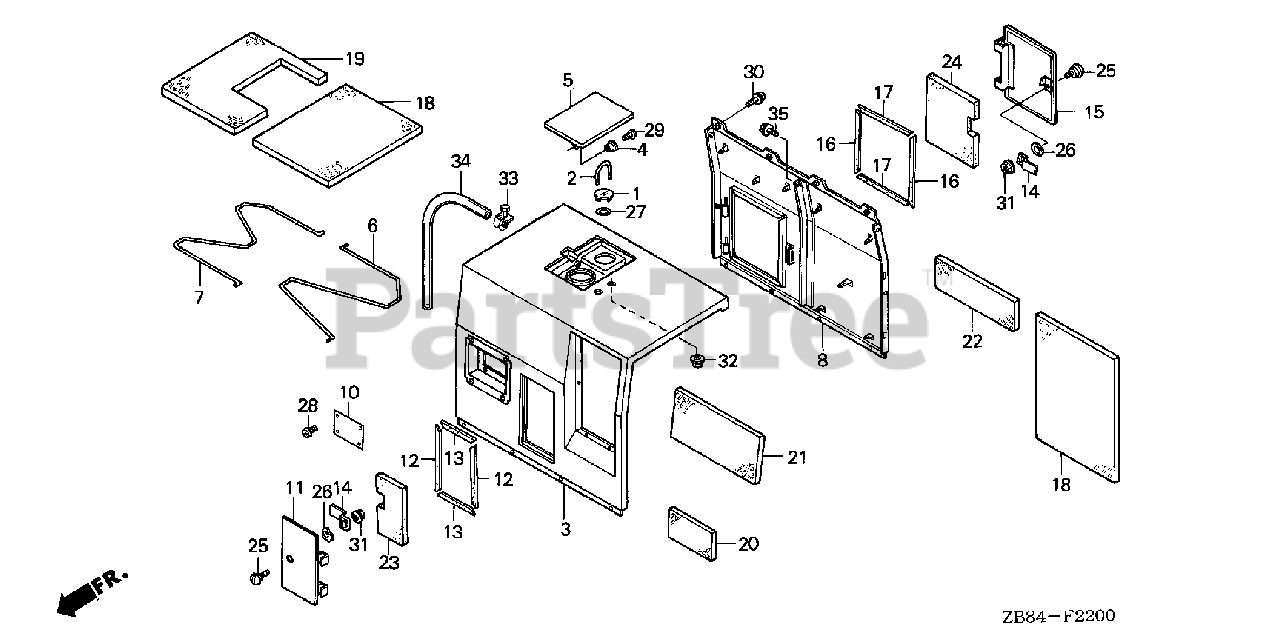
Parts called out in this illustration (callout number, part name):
1	CAP, FUEL METER
2	HOOK, HANGER
3	COVER, MAIN *R280* (POWER RED)
4	BUSH, FUEL CAP COVER
5	COVER, FUEL CAP *R8* (BRIGHT RED)
6	WIRE, R. INSULATOR HOLDER
7	WIRE, L. INSULATOR HOLDER
8	PANEL, RR. *R280* (POWER RED)
10	PLATE, REMOTE CONTROL CASE
11	LID, FR. MAINTENANCE *R8* (BRIGHT RED)
12	SEAL A, MAINTENANCE LID
13	SEAL B, MAINTENANCE LID
14	PLATE, MAINTNENANCE LID LOCK
15	LID, RR. MAINTENANCE *R280* (POWER RED)
16	SEAL, MAIN LID
17	SEAL, MAIN LID
18	INSULATOR A, MAINTENANCE LID COVER
19	INSULATOR B, MAINTENANCE LID COVER
20	INSULATOR C, MAINTENANCE LID COVER
21	INSULATOR E, MAINTENANCE LID COVER
22	INSULATOR, RR. PANEL (B)
23	INSULATOR, FR. MAINTENANCE LID
24	INSULATOR, RR. MAINTENANCE LID
25	BOLT, MAINTENANCE LID LOCK
26	WASHER, WAVE (12MM)
27	O-RING (56X2.4)
28	SCREW, PAN (5X10)
29	SCREW, HEADLIGHT SETTING
30	SCREW-WASHER (6X12)
31	NUT, FLANGE (6MM)
32	NUT, FLANGE (10MM)
33	CLIP, TUBE (A16)
34	BULK HOSE, VINYL (12X16X3000) (12X16X700)
35	BOLT, FLANGE (6X12)
